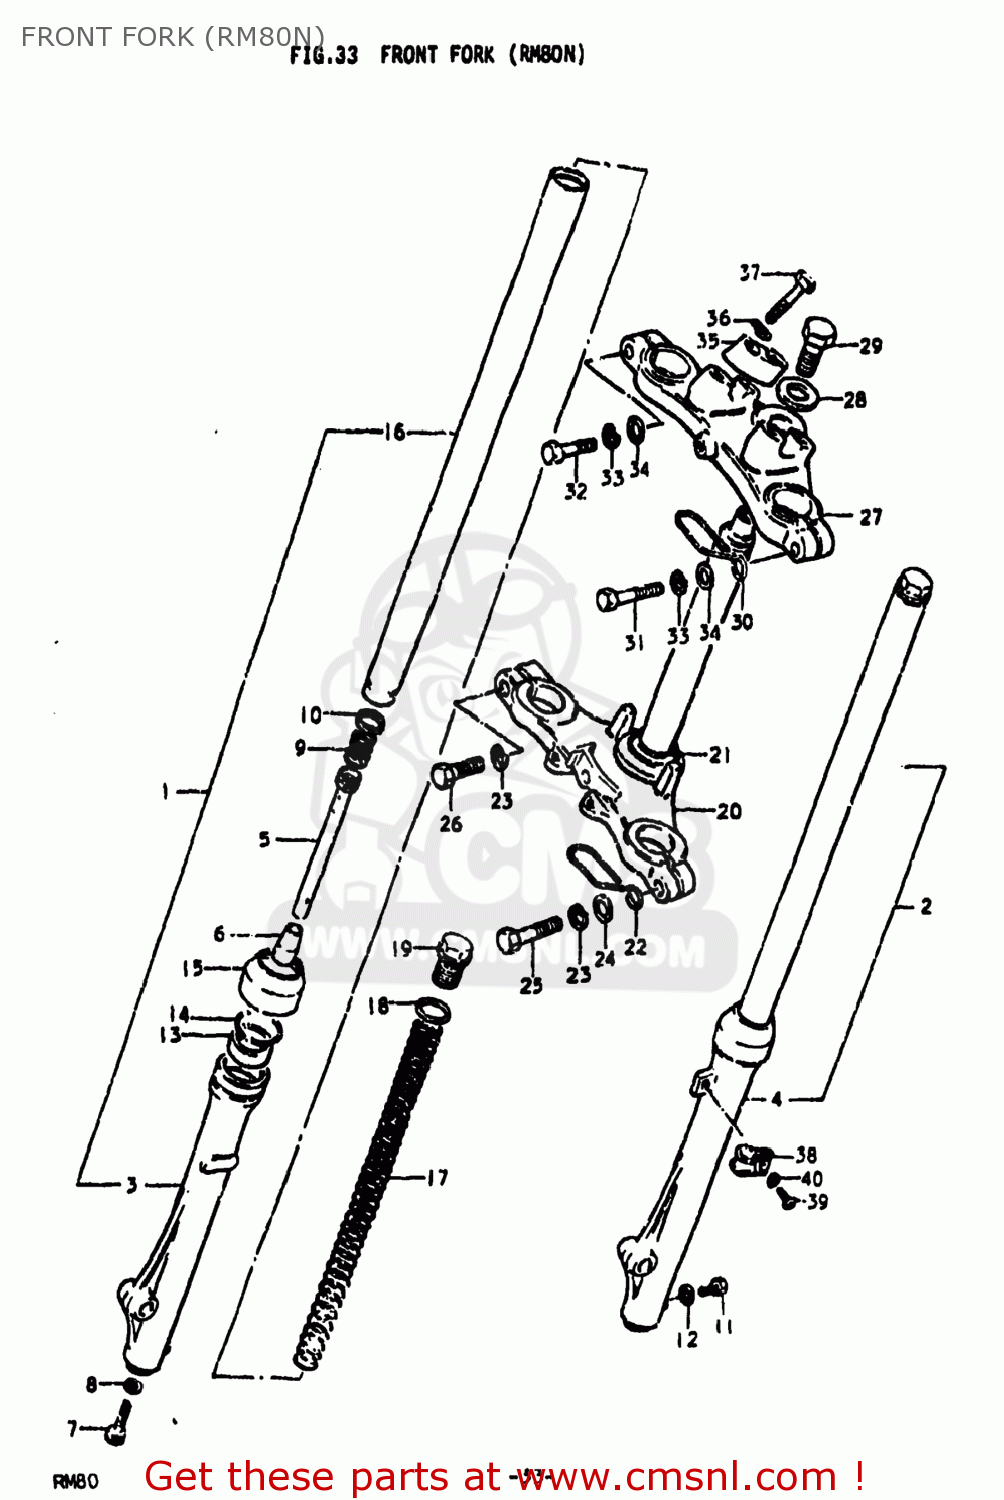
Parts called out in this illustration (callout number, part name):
1	DAMPER ASSEMBLY,RIGHT
2	DAMPER ASSEMBLY,LEFT
3	TUBE,OUTER,RIGHT
4	TUBE,OUTER,LEFT
5	CYLINDER,FRONT FORK
6	PIECE,OIL LOCK
7	BOLT(8X27)
8	GASKET (NAS)
9	SPRING,REBOUND
10	RING,PISTON
11	BOLT
12	GASKET,DRAIN,PLUG (NAS)
13	OIL SEAL,FRONT FORK
14	CIRCLIP,FORK OIL SEAL
15	DUST SEAL,FRONT FORK
16	TUBE,FORK,INNER
17	SPRING
18	O RING
19	BOLT
20	STEM,STEERING
21	RACE,STEERING OUTER LWR
22	CLAMP,METER CABLE
23	LOCK WASHER
24	WASHER
25	BOLT
26	BOLT,M10X1.25X
27	HEAD,STEERING STEM
28	WASHER(10.5X30X2.3)
29	BOLT
30	CLAMP,METER CABLE
31	BOLT 8X45
32	BOLT 8X40
33	LOCK WASHER
34	WASHER
35	HOLDER,HANDLEBAR
36	LOCK WASHER
37	BOLT
38	CLIP,FR BRAKE CABLE
39	SCREW
40	LOCK WASHER
